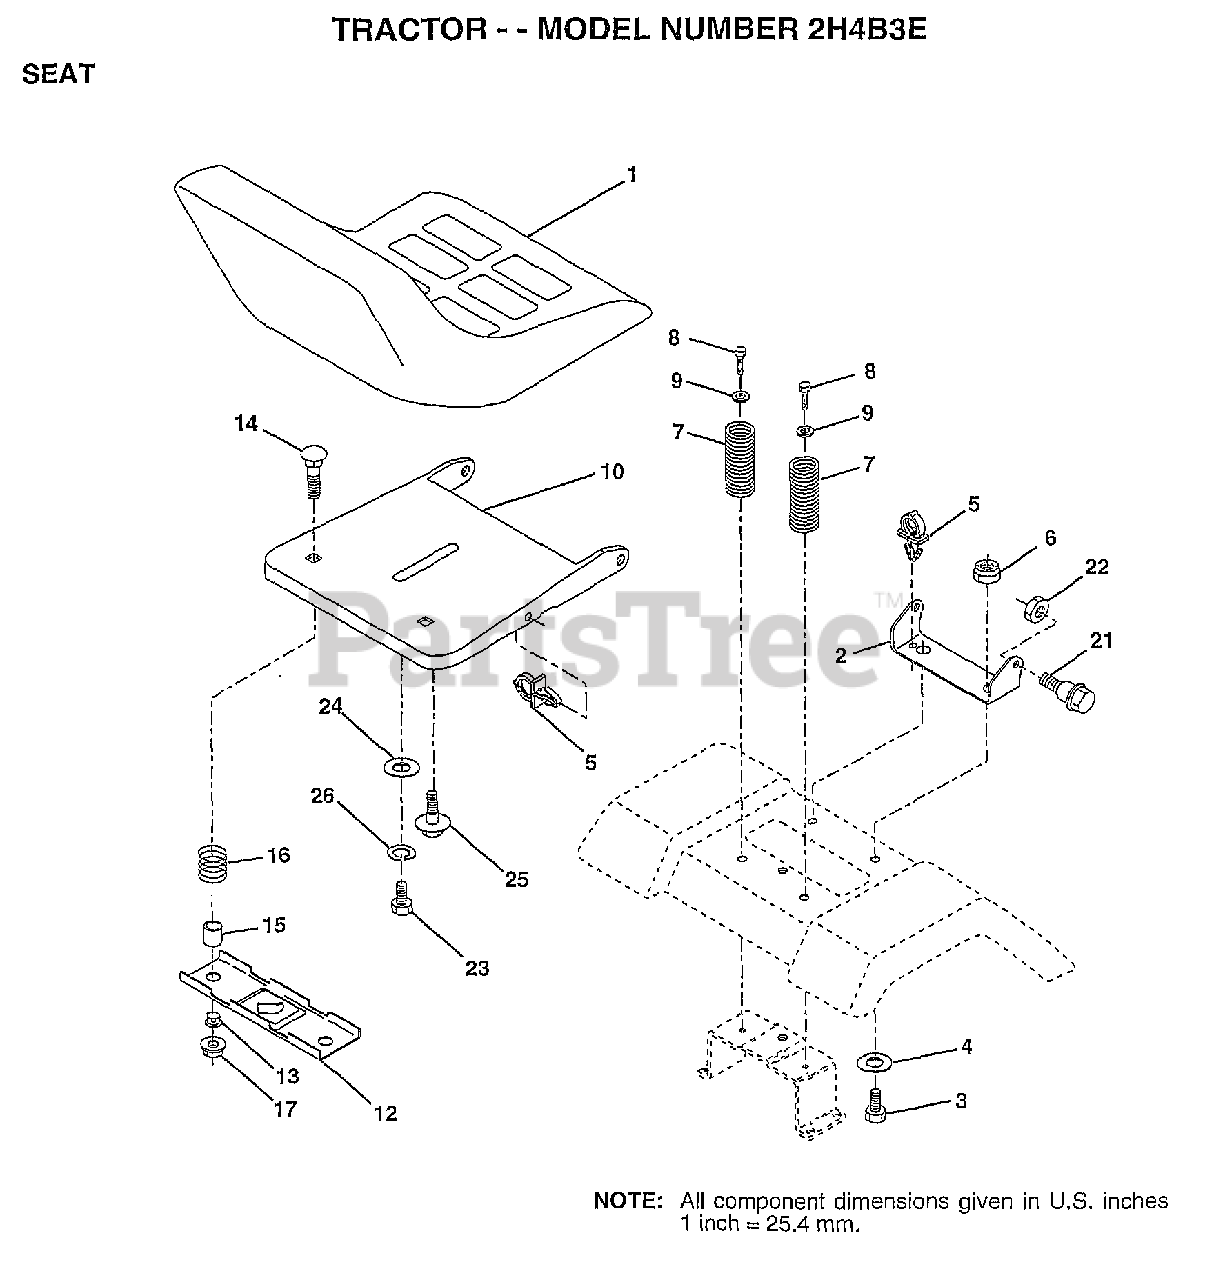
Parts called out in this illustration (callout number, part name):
2	BRACKET PVT SEAT
3	BOLT
4	WASHER PM
5	CLIP.PUSH-IN.HING
6	NUT
7	SPRING COMPRESSIO
8	SCREW GTV
9	WASHER
12	BRKT SWITCH
13	BUSHING
15	SPLIT SPACER
21	"BOLT,SHOULDER"
22	NUT
23	BOLT
24	WASHER
25	"BOLT,SHOULDER"
26	LOCKWASHER
